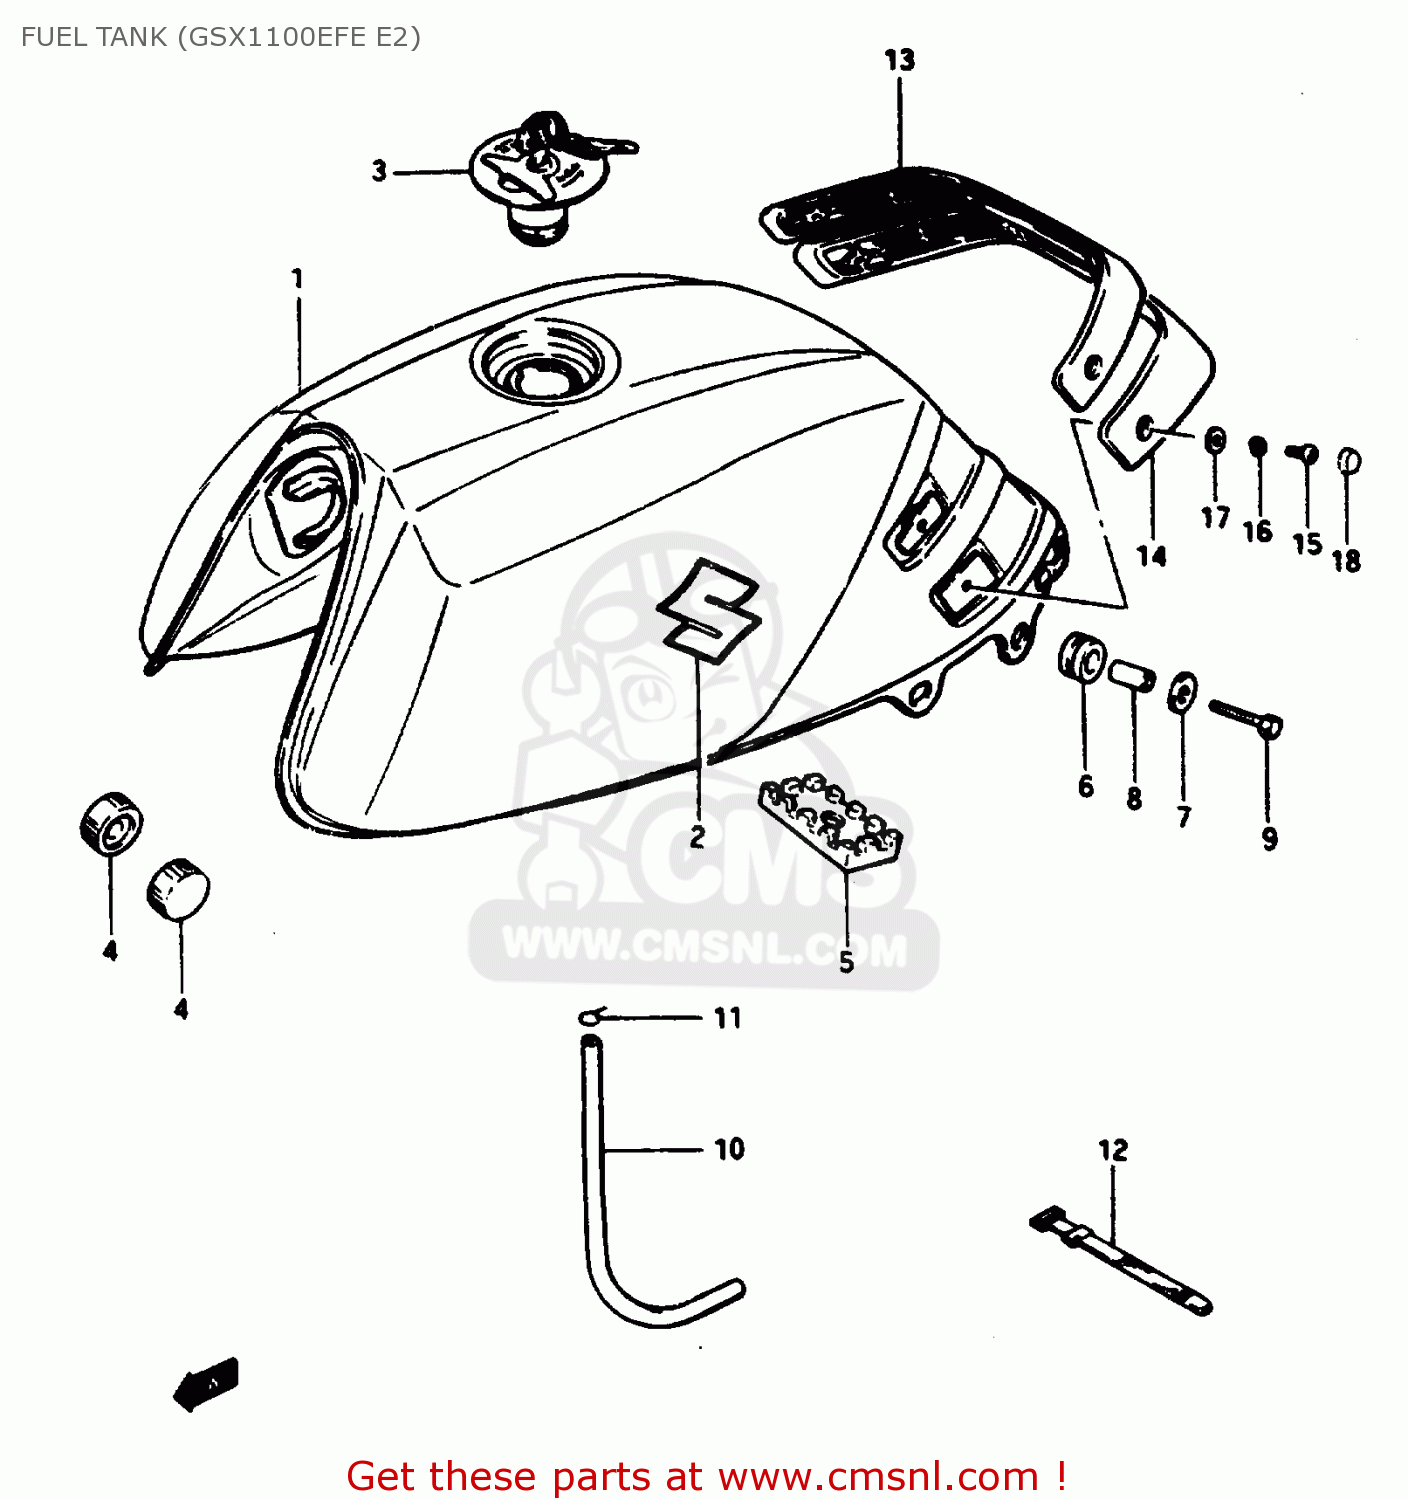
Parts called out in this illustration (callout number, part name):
1	TANK ASSY, FUEL (WHITE)
2	EMBLEM, "S" MARK
3	CAP ASSY,FUEL TANK
4	CUSHION
5	CUSHION,FUEL TANK CTR
6	CUSHION
7	WASHER (6.5X29X1.6)
8	SPACER (6.4X9X20)
9	BOLT 6X30
10	HOSE,FUEL
11	CLIP
12	CLAMP(L:187)
13	KNEE GRIP,FUEL TANK,UPPER
14	GRIP,FUEL TANK KNEE LWR
15	SCREW
16	LOCK WASHER
17	WASHER
18	CAP,KNEE GRIP
